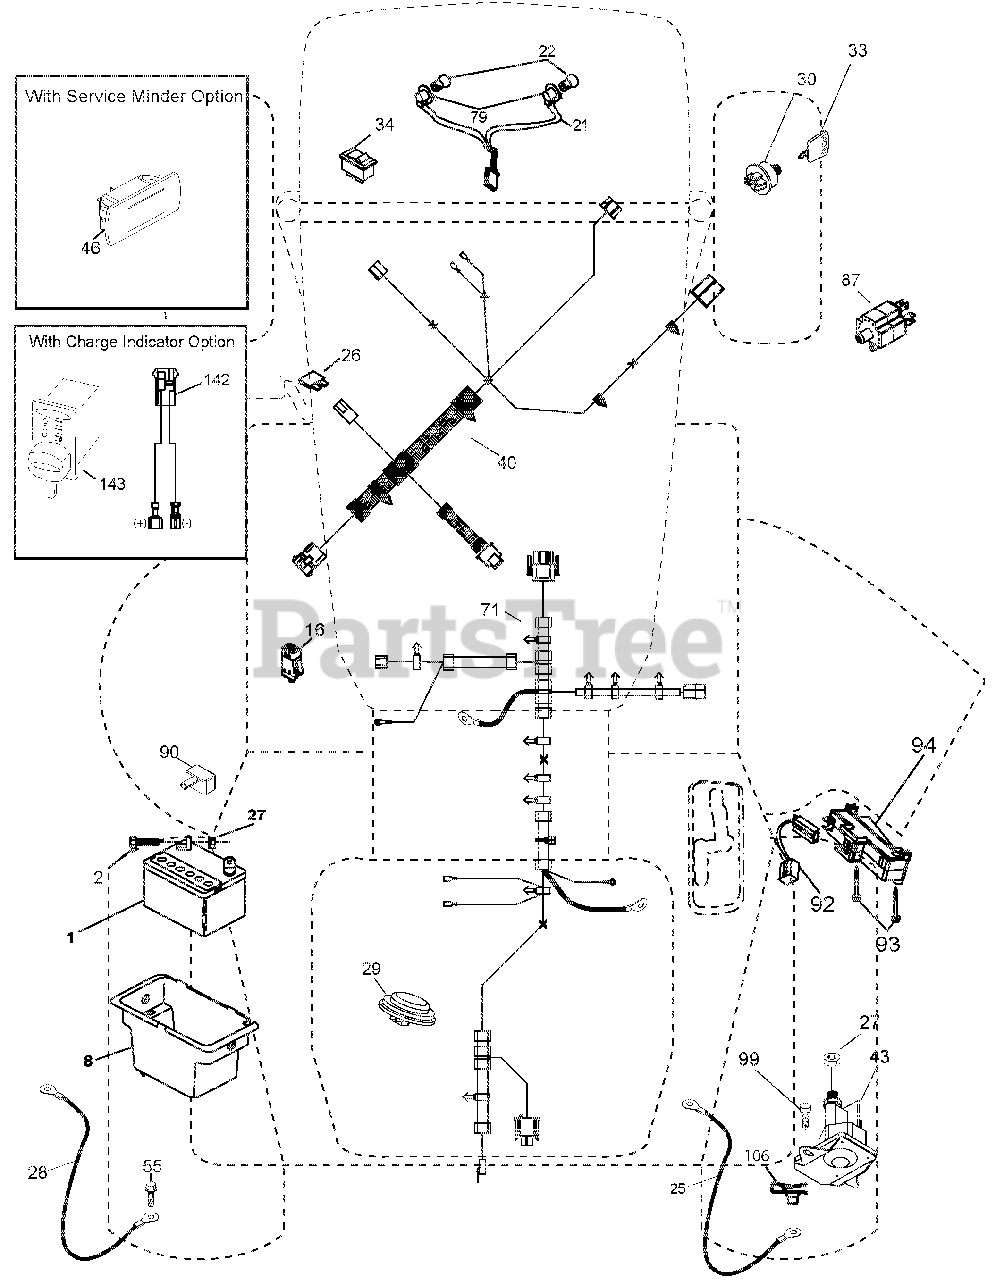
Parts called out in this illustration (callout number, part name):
1	BATTERY.12.VOLT.28.AMP.WET
2	BOLT.HEX.HD.1/4-20UNC X 3/4
8	BOX.BATTERY.MNT.REAR.LT.TEX.BL
16	SWITCH.INTERLOCK.NONO.GRAY
21	HARNESS ASM.LIGHT.22"(4152J)
22	BULB.LIGHT.#1156
25	CABLE STARTER 6 G4. BL/RED14.5
26	FUSE.20 AMP.
27	Nut, Keps Hex 1/4-20 unc
28	CABLE.BLACK.22"REAR BATT.TEX
29	SWITCH.SEAT.DELTA.OPC.9LB.
30	SWITCH.IGN.DLTA.P-IN.ROS
33	KEY/CHAIN.BLISTER PACK.GEN.USA
34	SWITCH.LIGHT/RESET.B/B/RED.
40	HARNESS.TEX.DASH (ELECTRICAL)
43	SOLENOID.W/BRASS PLUNGER.2005
55	SCREW.5/16-18X3/4.SMGML.TAP/R
71	HARNESS.IGN.CHASSIS.TEX
79	SOCKET ASM.BULB.TWISTLOCK
87	SWITCH.INTRLCK.CLUTCH.CABLE.TX
90	COVER TERMINAL BATTERY FR. TEX
92	HARNESS.PIGTAIL.CONSLE.ROS.MLK
93	SCREW.PLASTITE.10-14 X 2.0
94	MODUAL REVERSE ROS
